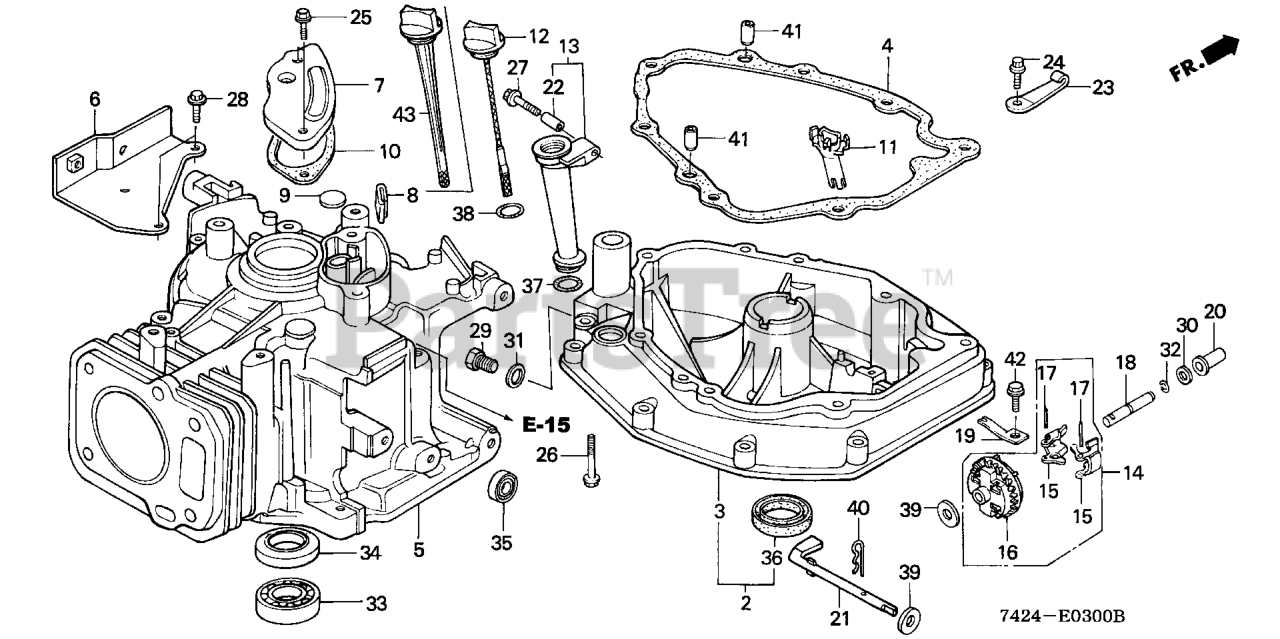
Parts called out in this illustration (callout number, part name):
2	PAN ASSY., OIL
4	GASKET, OIL PAN (HPE)
5	CYLINDER
6	PLATE, GUIDE
7	CAP, BREATHER CHAMBER
8	FILTER, BREATHER
9	VALVE, BREATHER
10	GASKET, BREATHER CHAMBER
11	PIPE, OIL DEFENSE
13	EXTENSION, OIL FILLER (106MM)
14	GOVERNOR ASSY.
15	WEIGHT, GOVERNOR
16	HOLDER, GOVERNOR WEIGHT
17	PIN, GOVERNOR WEIGHT
18	SHAFT, GOVERNOR HOLDER
19	PLATE, GOVERNOR SHAFT HOLDER
20	SLIDER, GOVERNOR
21	SHAFT, GOVERNOR ARM
22	COLLAR, EXTENSION Use up to Engine SN 1257294.
23	STOPPER, CABLE
24	BOLT, FLANGE (6X14)
25	BOLT, FLANGE (6X12) (CT200)
26	BOLT, FLANGE (6X28) (CT200) Use up to Engine SN 1530314.
27	BOLT, FLANGE (6X32)
28	BOLT, FLANGE (6X20) (CT200)
29	BOLT, DRAIN PLUG
30	WASHER, THRUST (6MM)
31	WASHER, DRAIN PLUG (10.2MM)
32	CLIP, GOVERNOR HOLDER
33	BEARING, RADIAL BALL (62/22)
34	OIL SEAL (22X35X6)
35	OIL SEAL (6X11X4)
36	OIL SEAL (25X38X7)
36	OIL SEAL (25X38X7) (ARAI)
37	O-RING (22.5X2.2) Use from Engine SN 1257295.
38	O-RING (26X2.7)
39	WASHER, PLAIN (6MM)
40	PIN, LOCK (8MM)
41	PIN A, DOWEL (8X14)
42	BOLT, FLANGE (6X12) Use from Engine SN 2086984.
43	GAUGE, OIL LEVEL Use up to Engine SN 1257294.
